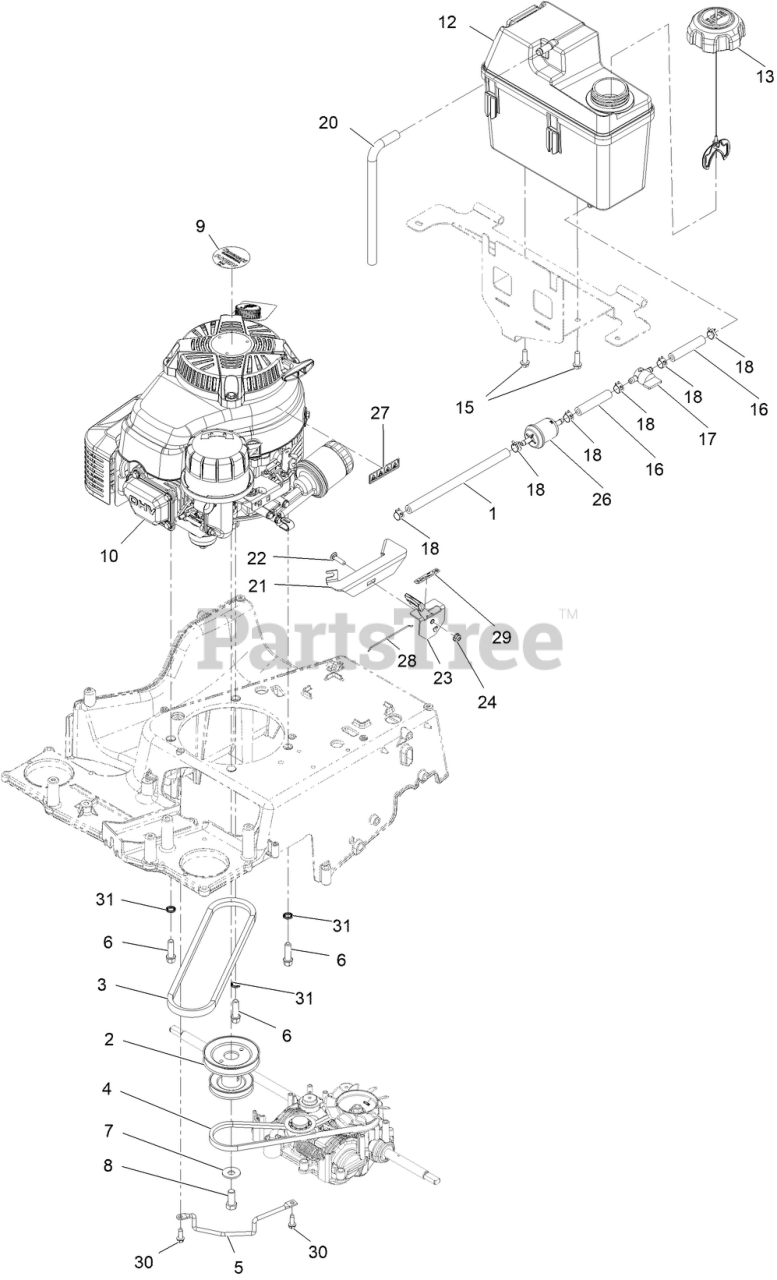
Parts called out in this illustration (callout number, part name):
1	HOSE-FUEL
2	Pulley-Engine
5	ROD-GUIDE, BELT
6	SCREW-TAPTITE
7	WASHER-BELLEVILLE
8	SCREW-HH
12	TANK-FUEL
13	CAP-FUEL
15	SCREW-HWH
16	HOSE-FUEL
17	VALVE-FUEL
18	CLAMP-HOSE
20	HOSE-VENT, CANISTER
21	BRACKET-MOUNT, THROTTLE
22	SCREW-CARR
23	CONTROL-THROTTLE
26	FILTER-FUEL
27	DECAL-WARNING, ENGINE
28	WIRE-CONTROL
29	DECAL-THROTTLE, CHOKE
30	SCREW-HWHTF
31	WASHER-LOCK
